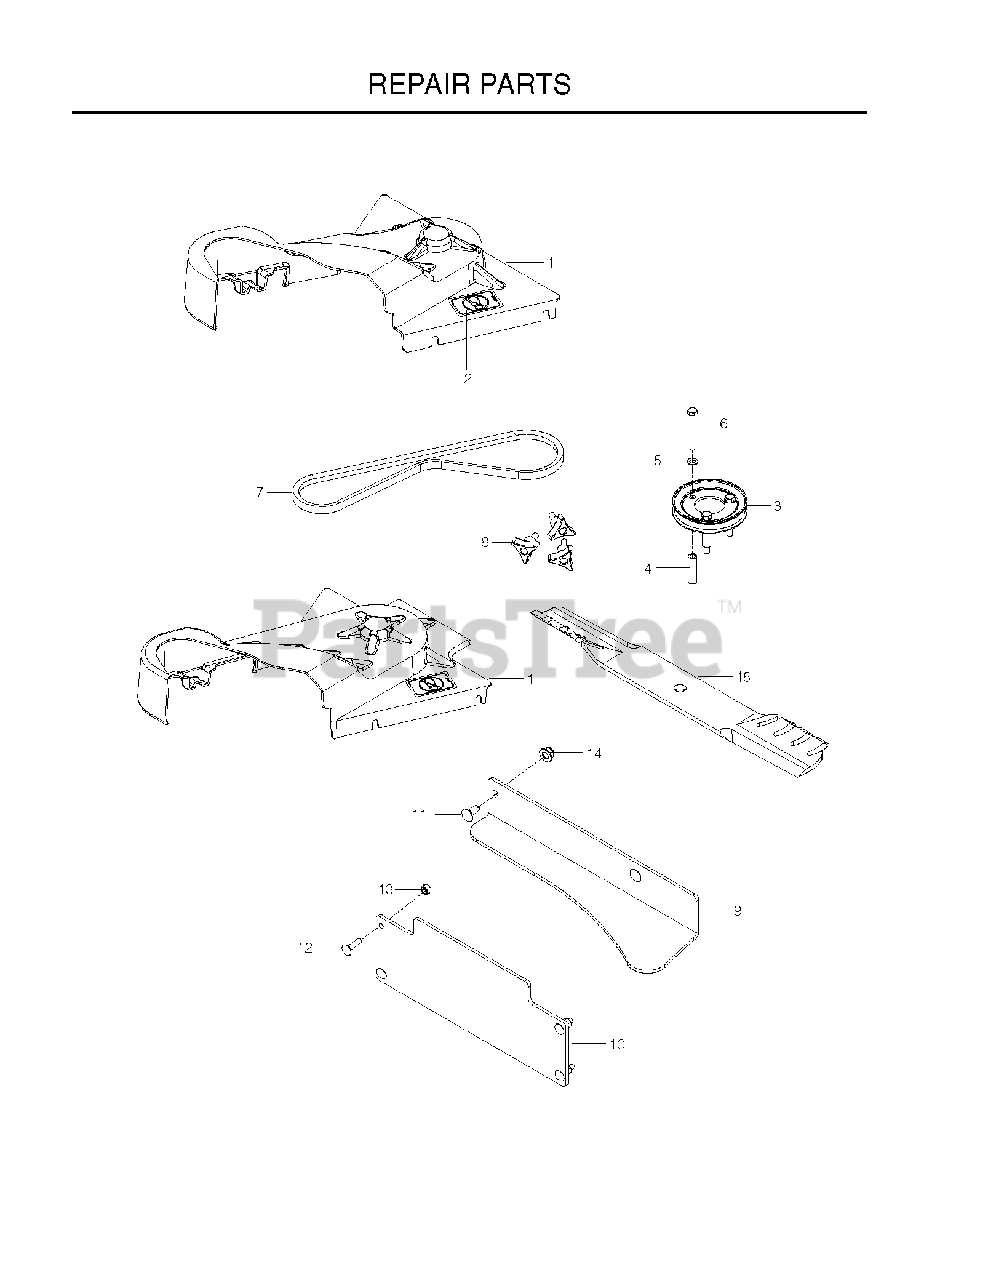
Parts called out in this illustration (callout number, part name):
1	SHIELD, LOWER, 54"
2	DECAL, NO STEP
3	PULLEY, DRIVE, 54"
4	SPACER, PULLEY
5	WASH 5/16 DISC SPRING ZD
6	BOLT 5/16C X 2 1/2
7	BELT, DRIVE
8	KNOB W/STUD
9	BAFFLE, RH, BLACK
10	BAFFLE, LH, BLACK
11	RHSNB, 1/4-20 X 1, GR5
12	BOLT 5/16C X 3/4" CARRIAGE
13	NUT 1/4-20 NYLOC
14	5/16-18 NYLOC FLANGE NUT
15	BLADE, 19" GATOR, 1.25" LIFT
